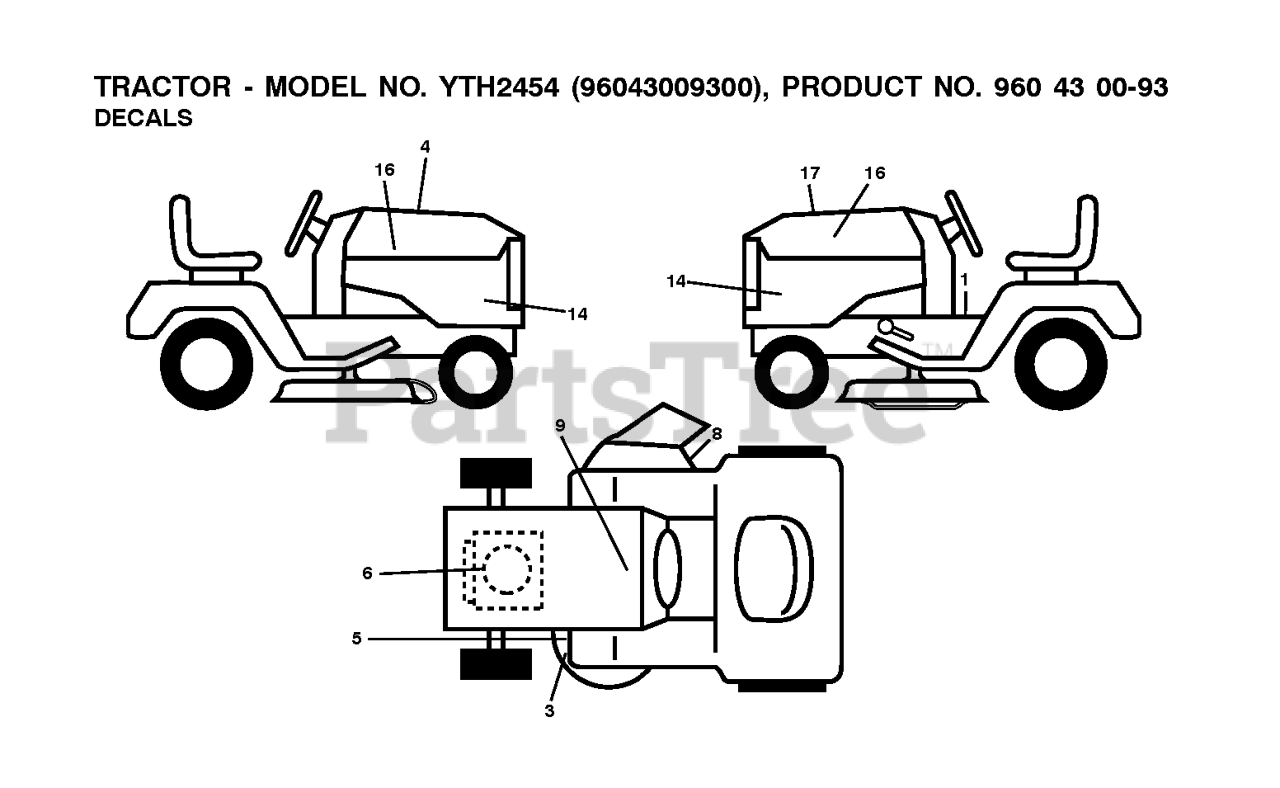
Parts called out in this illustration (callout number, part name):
1	DECAL.FENDER.WARNING.ENG
3	DECAL.WARN.KEEP.HAND.AWAY
4	DECAL.WARNING.CUST.RESP.E85.
5	DECAL.MOWER
6	DECAL, ENGINE, HP
8	DECAL.MOWER.SCH.48/54
9	DECAL BTRY SYMBOLS
14	DECAL.PNL.
16	DECAL.HOOD.LOGO.ORANGE.HUSQVAR
